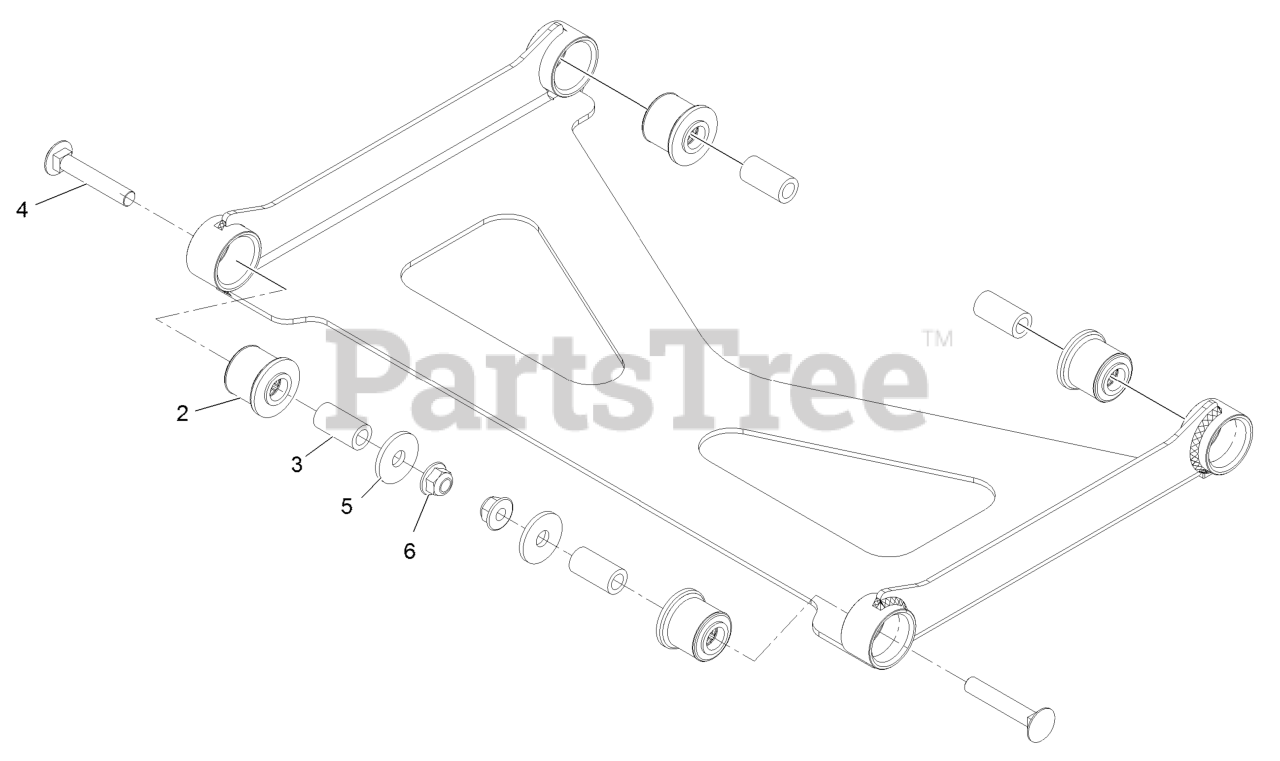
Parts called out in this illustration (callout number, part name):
2	Bushing-Rubber, Suspension
4	Bolt-Carriage 3/8-16 X 2 1/4
5	Washer
6	Nut-Nyloc 3/8-16 Flg
